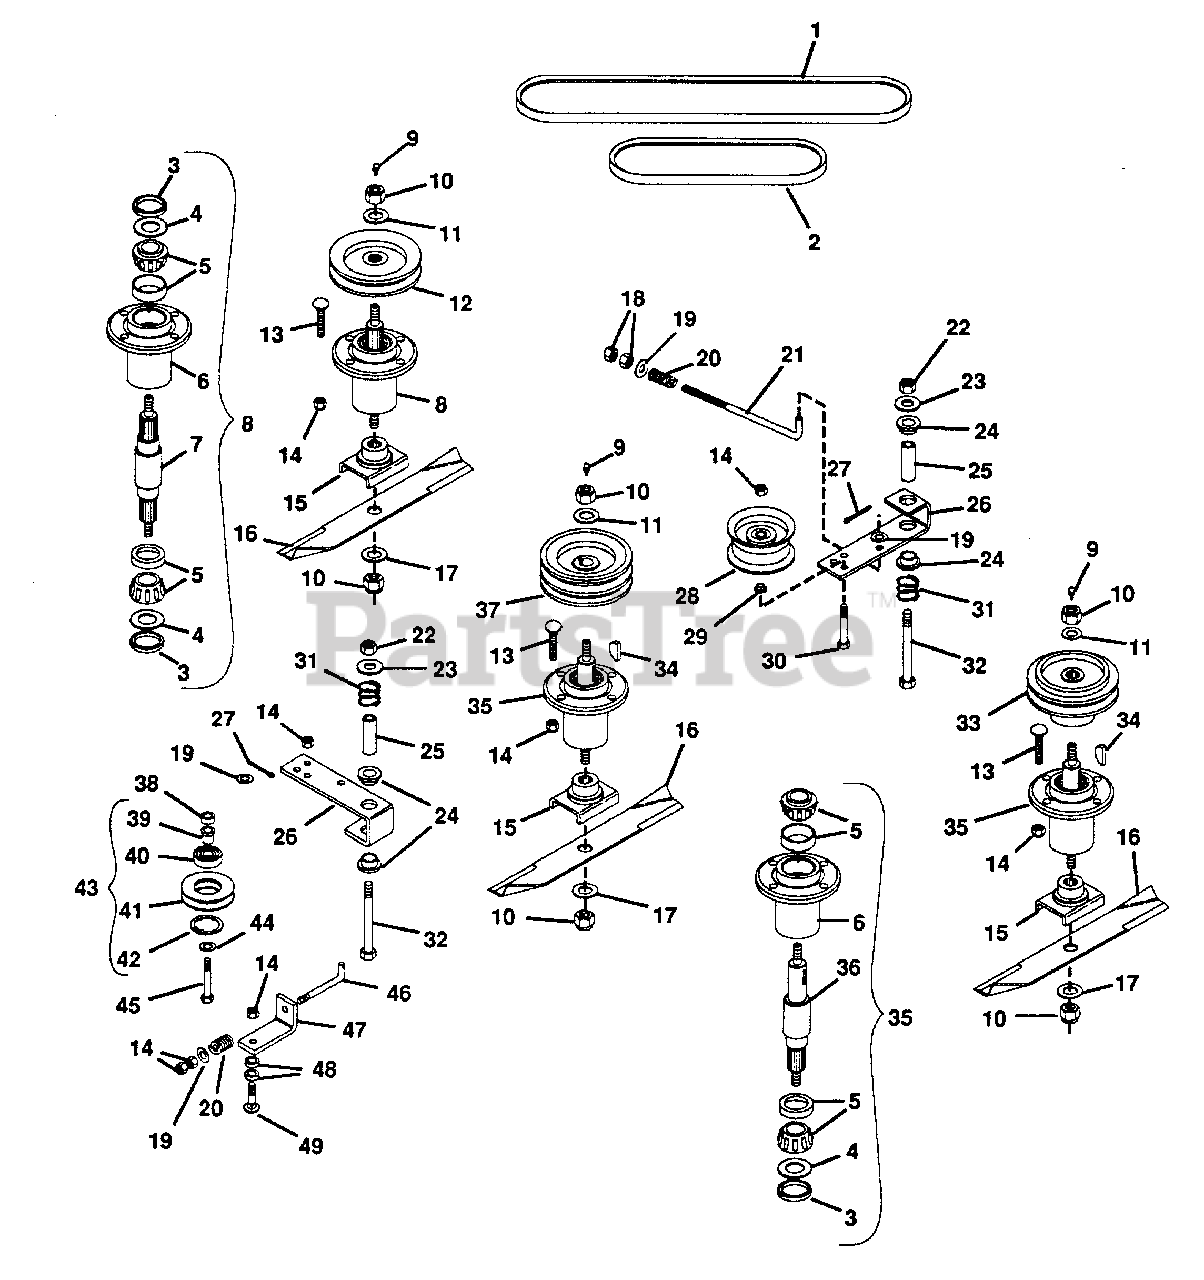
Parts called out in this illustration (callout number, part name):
1	V-BELT, HA-RAW EDGE
2	V-BELT, HA-RAW EDGE
3	SPCR 1.391X1.980X.313 PM
4	WSHR-FL-STL .97X1.865X.03
5	ASM,BEARING CUP&CONE
6	HSG,BEARING
7	SPINDLE SHAFT SERVICE KIT
8	MAINTENANCE FREE SPINDLE ASSY
9	FTG,LUBE 1/8
10	NUT-LK-NYL .625-11 YWZC
11	WSHR-FL-STL .687X1.312X.15 YWZ
12	SHEAVE
13	BLT-RDHDSQNK .38-16X1.50 G5YZ
14	NUT-LK-NYL .38-16 YWZC
15	WELM'D, BLADE CRADLE
16	BLADE
17	WSHR-FL-STL.656X1.31X.095 YWZ
18	NUT-HEX .375-24 YWZC
19	WSHR-FL-STL.406X.812X.065 YWZ
20	SG-COMP .125X.78X1.00 YWZ
21	ROD,IDLER
22	NUT-LK-CTR .50-13 YWZC
23	WSHR-FL-STL.50X1.25X.083 YWZC
24	BSHG-FLG .762X1.0X.580X1.48 NY
25	SPACER .560X.750X2.437 ST
26	ARM,IDLER PIVOT
27	PIN-CTR .09X.75 EXTPRSQCT YWZ
28	IDLER-FLAT 4.00X.38 (2.00 W)
29	BSHG-FLG .406X.88X.270X.140
30	BLT-HEX .38-16X2.25 GR5 YWZC
31	SG-COMP .085X.80X1.00 WLD36
32	BLT-HEX .50-13X3.25 GR5 YWZC
33	SHEAVE
34	KEY-WDRF .25X1.00 HRD #15
35	MAINTENANCE FREE SPINDLE ASSY
36	SPINDLE SHAFT SERVICE KIT
37	SHEAVE,MOWER SPINDLE
38	BUSH.,S.406X.625X.480 ST
39	BSHG-FLG .786X1.0X.79
40	BRG-BALL 1.85X.787X.55
41	SHEAVE,IDLER
42	RG-RTNG-INT 2.054X.062
43	ASM,IDLER SHEAVE
44	WSHR-FL-STL .375X1.125X.065YWZ
45	BLT-HEX .38-16X2.00 GR5 YWZC
46	ROD,IDLER
47	BRKT,BELT TENSIONER
48	BUSH.,S.391X1.00X.250 ST
49	BLT-RDHDSQNK .38-16X1.75 G5YZ
